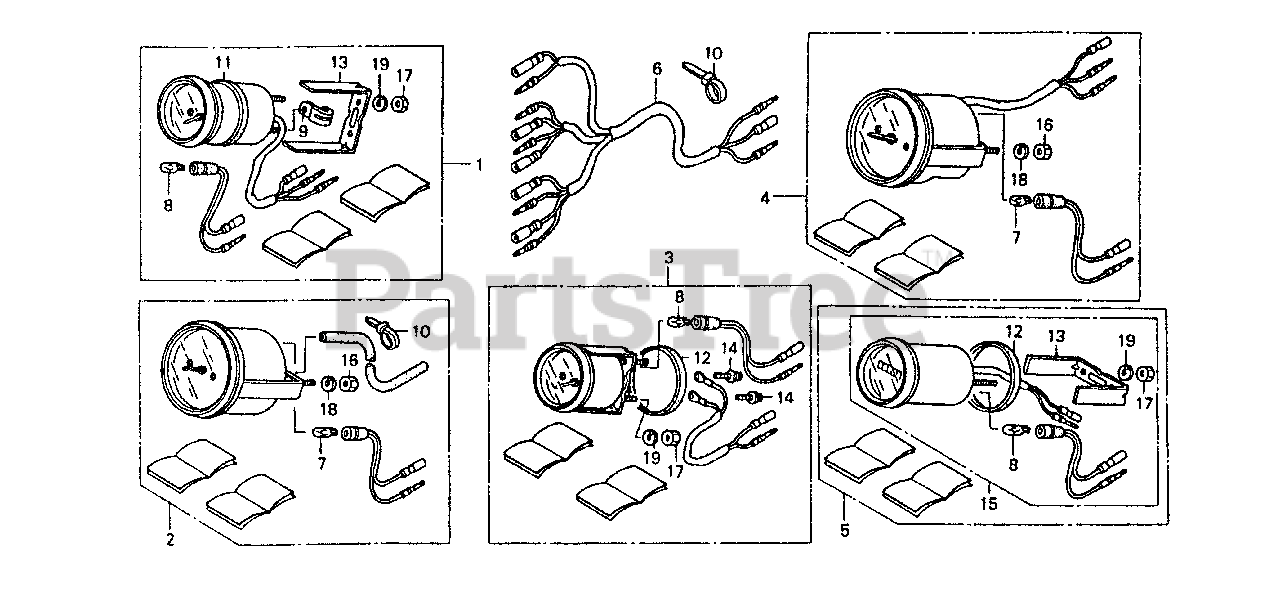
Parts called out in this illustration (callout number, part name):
1	METER KIT, TRIM (WHITE)
1	METER KIT, TRIM *NH1D* (B) (BLACK)
2	METER KIT, SPEED
2	METER KIT, SPEED *NH1D* (B) (BLACK)
3	METER KIT, VOLT
3	METER KIT, VOLT *NH1D* (B) (BLACK)
4	METER KIT, TACHO
4	METER KIT, TACHO *NH1D* (B) (BLACK)
5	METER KIT, HOUR (NOT AVAILABLE)
5	METER KIT, HOUR *NH1D* (B) (BLACK)
6	HARNESS ASSY., METER (B)
7	BULB, WEDGE BASE (12V1.7W) (NIPPON SEIKI)
8	BULB/SOCKET (T4.8) (NOT AVAILABLE)
10	BAND, SELF-LOCK
14	SCREW-WASHER (3X22)
15	METER ASSY., HOUR
16	NUT, HEX. (5MM)
17	NUT, HEX. (4MM)
18	WASHER, SPRING (5MM)
19	WASHER, SPRING (4MM)
